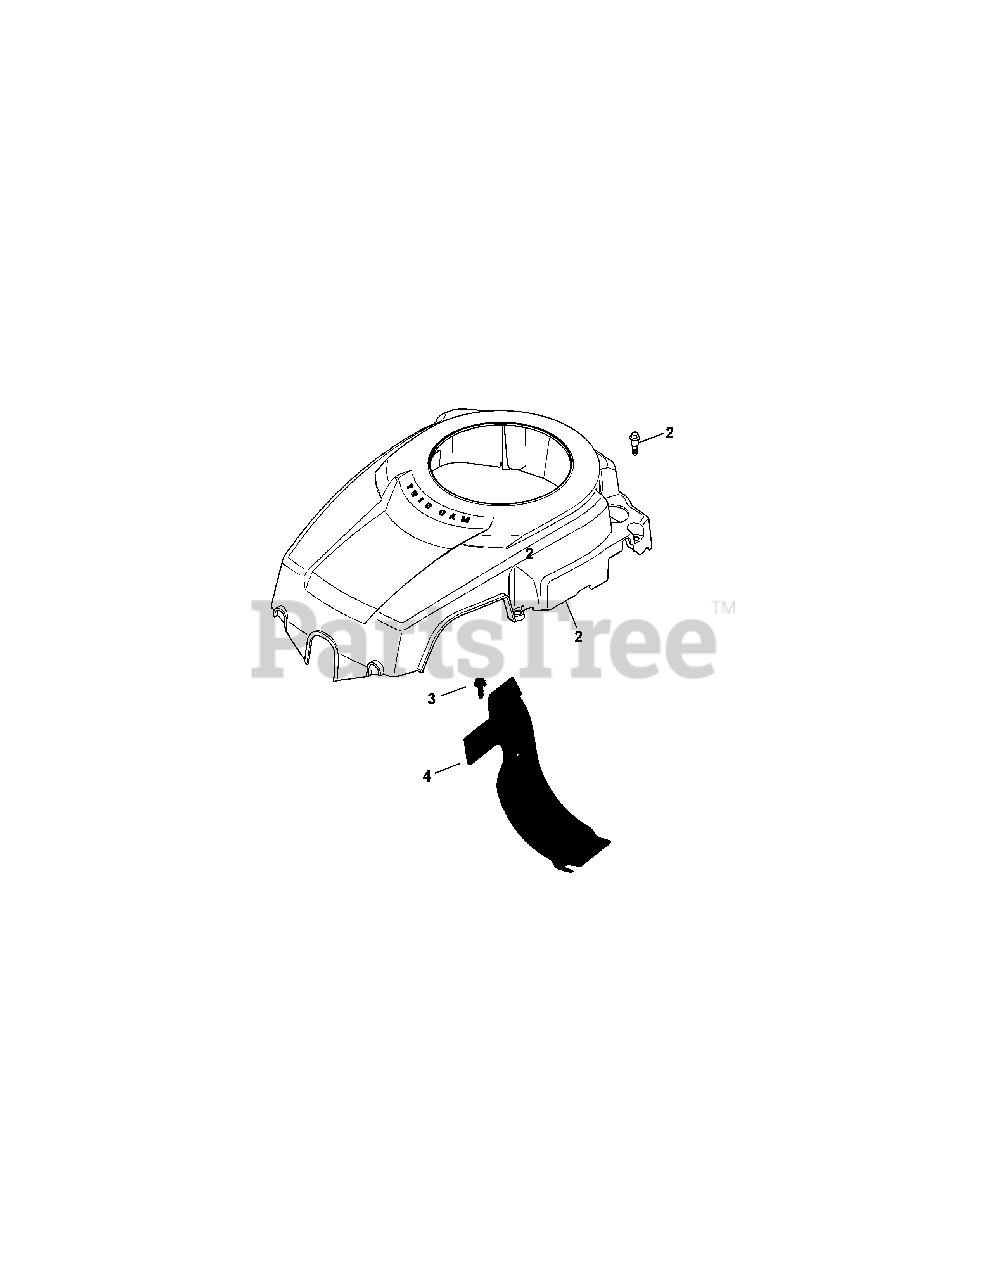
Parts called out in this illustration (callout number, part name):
1	Blower Housing Kit
2	Shd. Thd. Frm. Screw, M6 X 1 X 26
3	Flg. Thd. Frm. Screw, M6 x 1.0 x 16
4	Barrel Baffle
